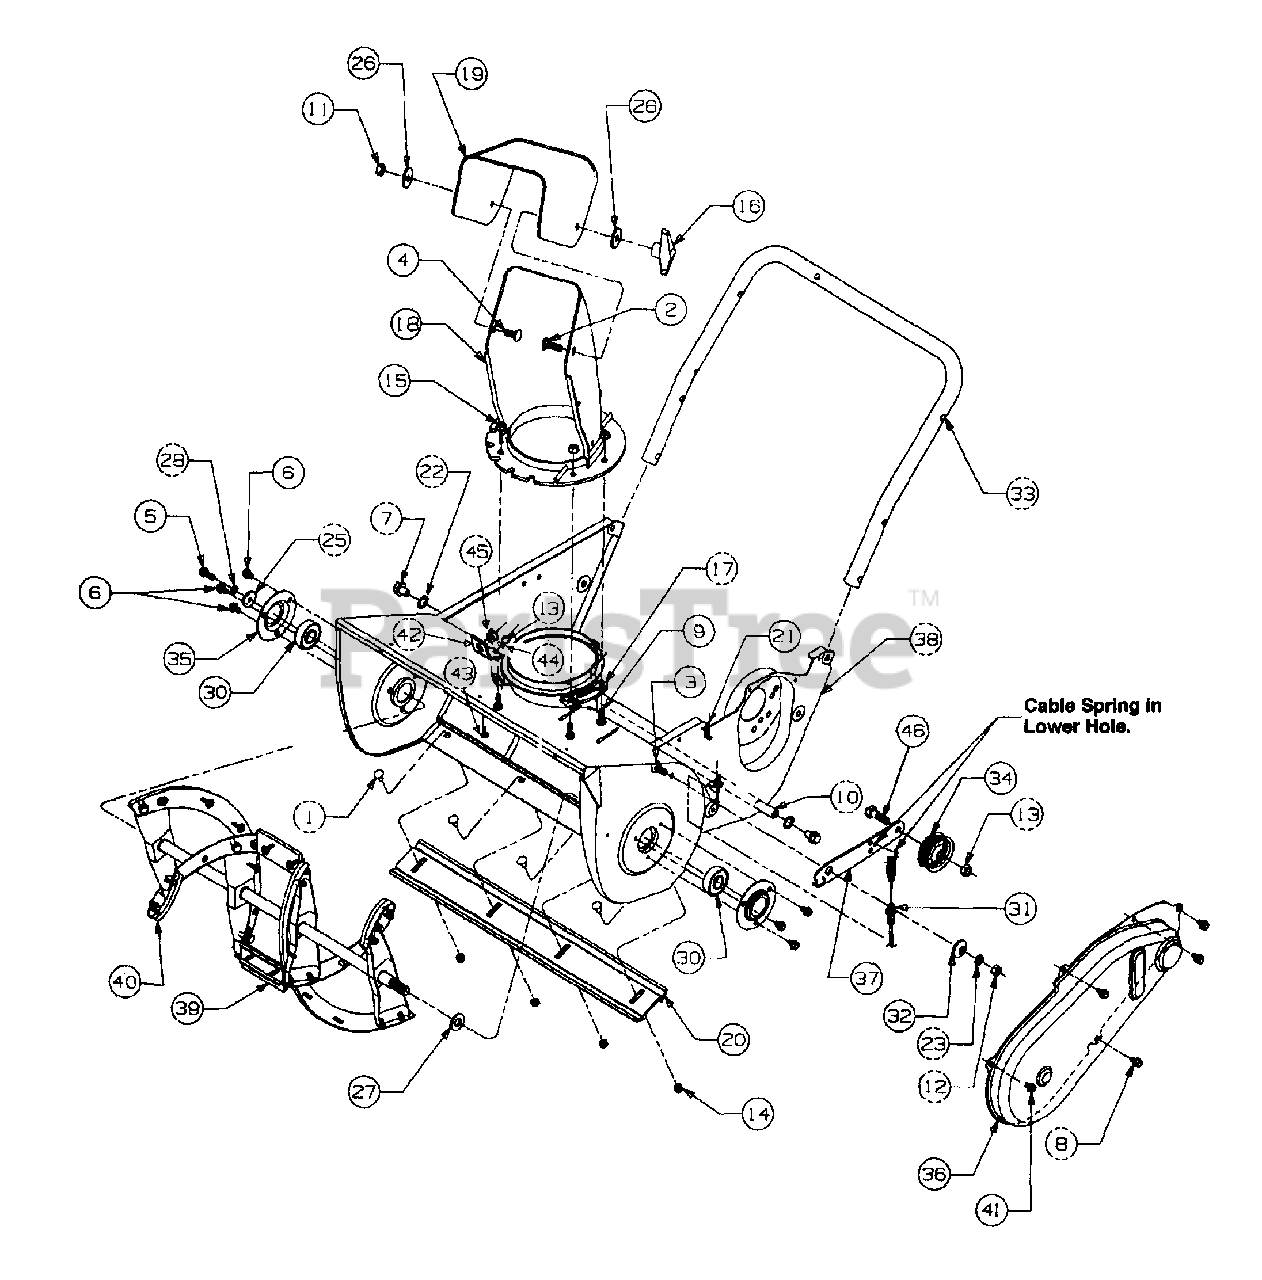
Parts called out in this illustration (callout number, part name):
1	Carriage Bolt
2	Carriage Bolt
3	Pan Head Screw
4	Carriage Bolt
5	Hex Washer Screw
6	Hex Washer Screw
7	Hex Washer Screw
8	Hex Washer Screw
9	Hex Cap Screw
10	Axle
11	Hex Center Lock Nut
13	Hex Lock Nut
15	Hex Lock Flanged Nut
17	Chute Keeper
18	Lower Chute
19	Upper Chute
20	Shave Plate
21	Extension Spring
22	Flat Washer
23	Lock Washer
25	Flat Washer
27	Flat Washer
28	Lock Washer
30	Ball Bearing
31	Cable - Clutch
40	Auger Rubber
41	Hex Washer Screw
44	Bell Washer
45	Bushing
46	Hex Screw
